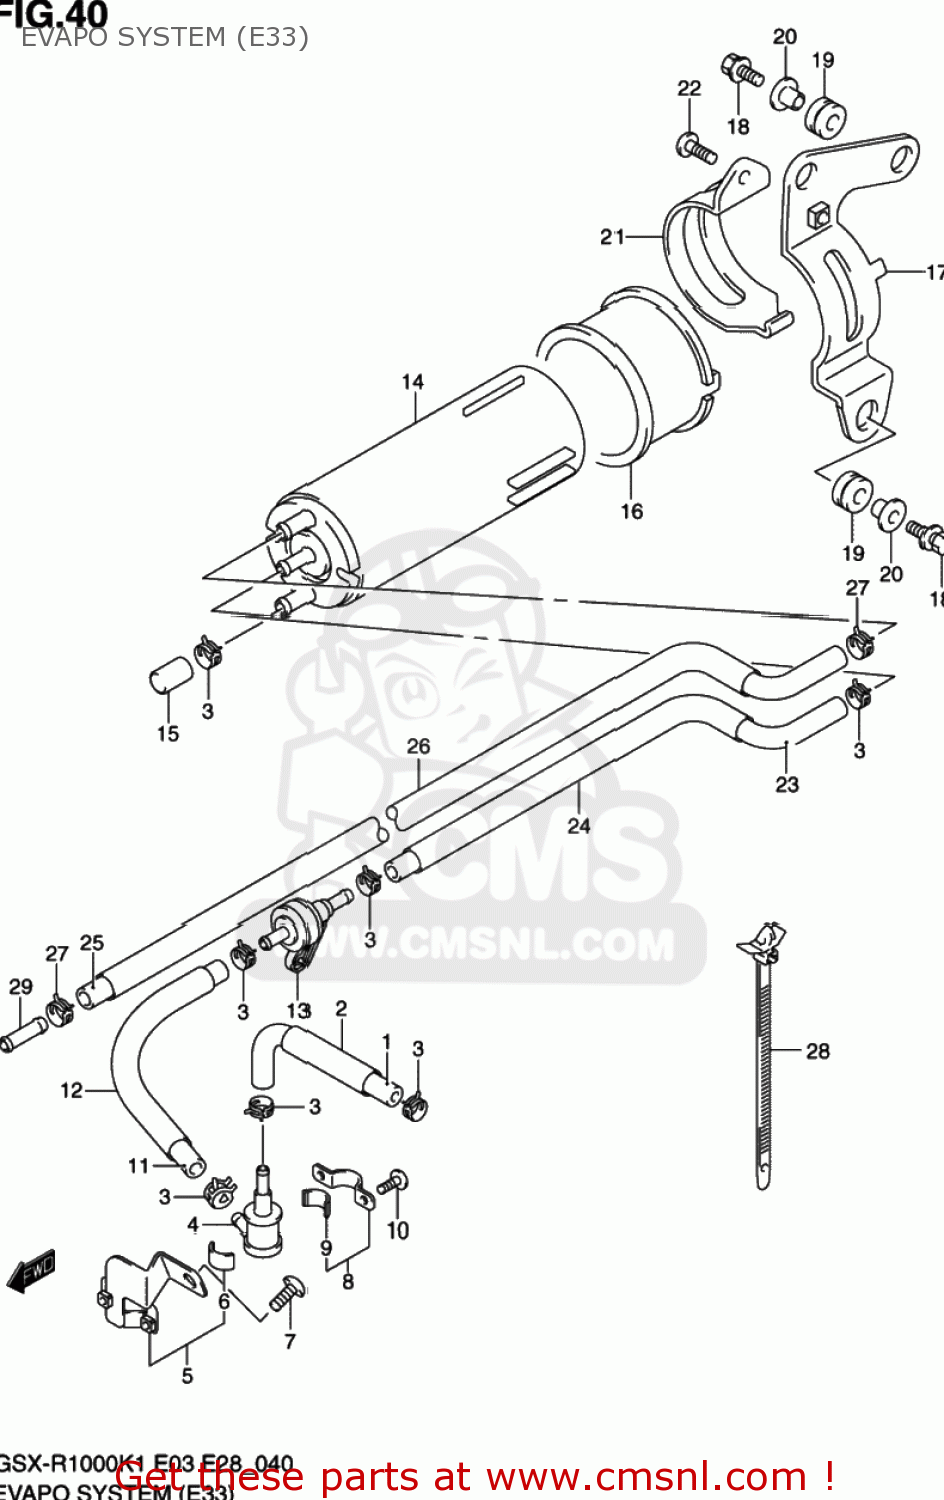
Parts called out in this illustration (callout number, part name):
1	HOSE,TANK & BREATHER VALVE
2	PROTECTOR(14.5X15.5X600)
3	CLIP
4	VALVE,FUEL TANK BREATHER
5	PLATE,TANK BREATHER VALVE
6	CUSHION
7	SCREW 6X10
8	PLATE,FUEL TANK BREATHER NO.2
9	CUSHION
10	SCREW
11	HOSE(5.4X11.4X600)
12	PROTECTOR(14.5X15.5X600)
13	VALVE,2 WAY & BREATHER VALVE
14	CANISTER ASSY,CHARCOAL
15	CAP,OD:11.5
16	CUSHION,CANISTER
17	BRACKET,CANISTER
18	BOLT(6X25)
19	CUSHION
20	WASHER
21	HOLDER,CANISTER
22	SCREW 6X10
23	HOSE(5.4X11.4X600)
24	PROTECTOR(14.5X15.5X600)
25	HOSE(5.4X11.4X760)
26	HOSE
27	CLIP
28	CLAMP(L:120)
29	UNION
